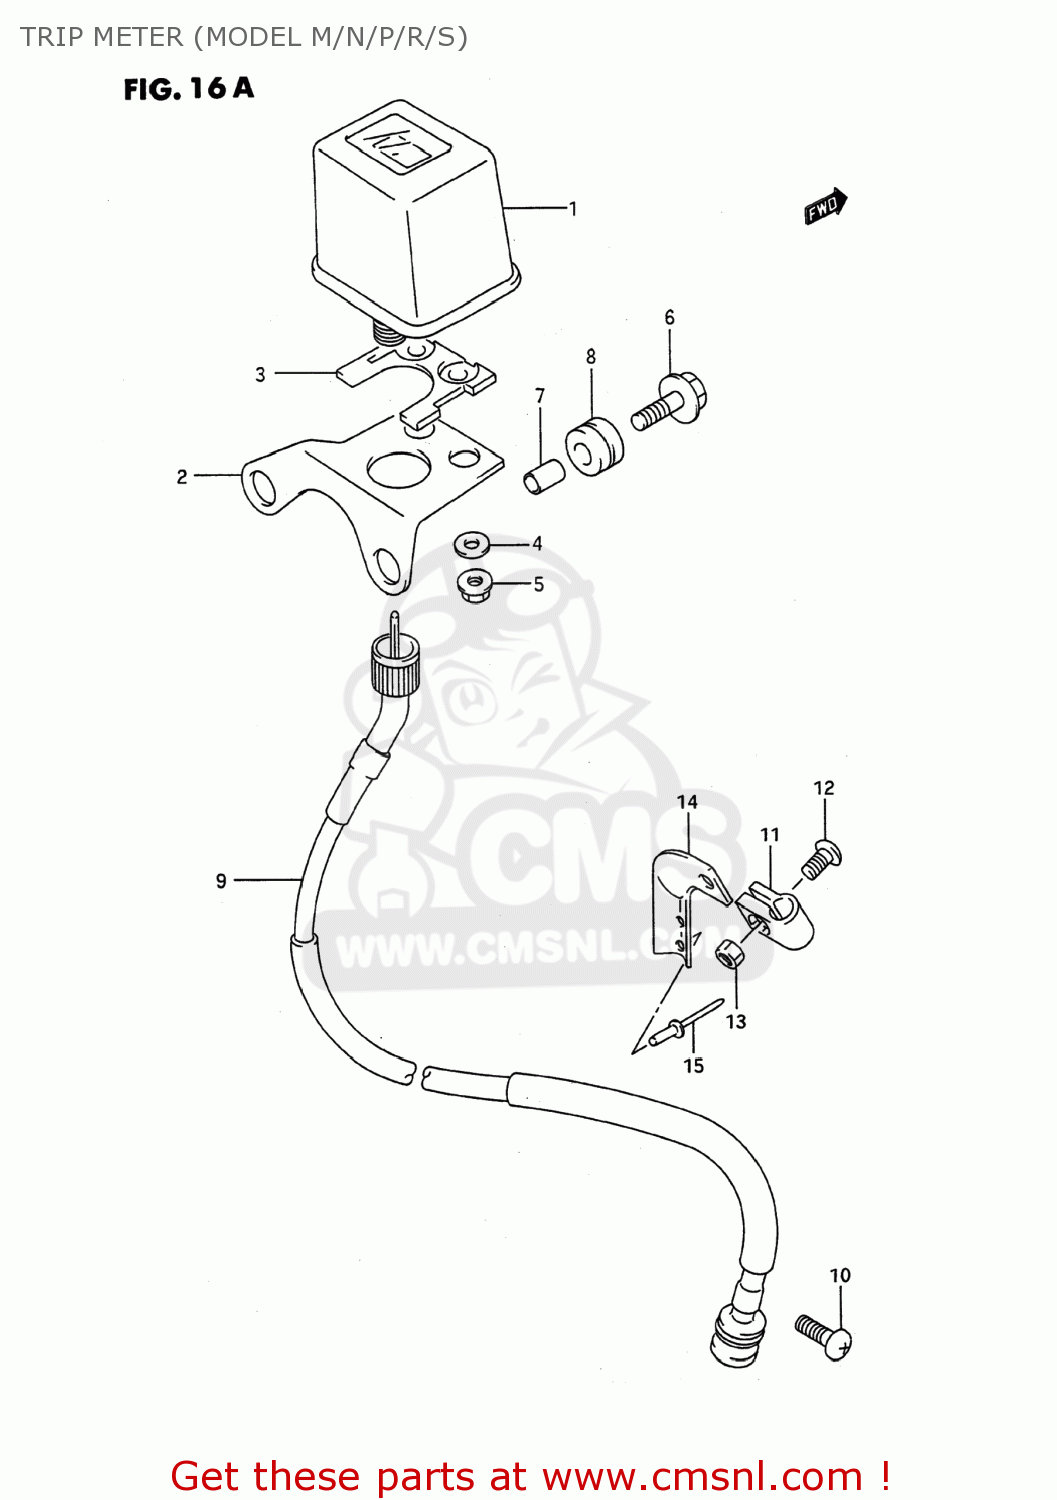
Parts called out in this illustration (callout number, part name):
1	TRIP METER
2	BRACKET
3	CUSHION
4	WASHER,METER
5	NUT
6	BOLT(6X25)
7	SPACER (6.1X8X9.5)
8	CUSHION
9	CABLE ASSEMBLY,TRIPMETER
10	SCREW
11	CLAMP,FR BRAKE CABLE
12	SCREW
13	NUT
14	BRACKET,METER CABLE GUIDE
15	RIVET
